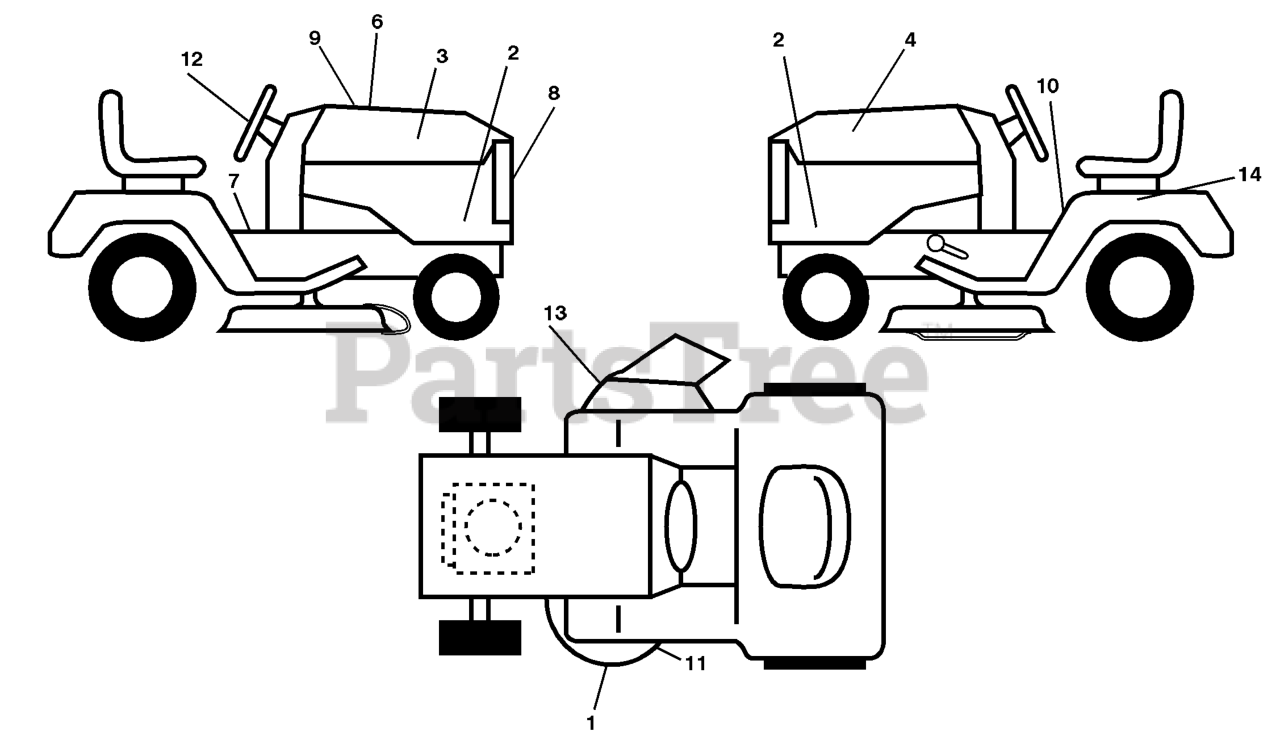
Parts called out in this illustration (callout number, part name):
1	DECAL, MOWER HEAVY DUTY
2	HOOD DECAL, YTH2148
3	DECAL, HOOD RH
4	DECAL, HOOD LH
6	DECAL HOOD CUST. RESP.
10	DECAL FENDER DANGER
11	DECAL V-BELT SCHEMATIC
12	DECAL.STEERING.HUSQ.BLUE
13	DECAL.WARN.KEEP.HAND.AWAY
14	DECAL BTRY SYMBOLS
